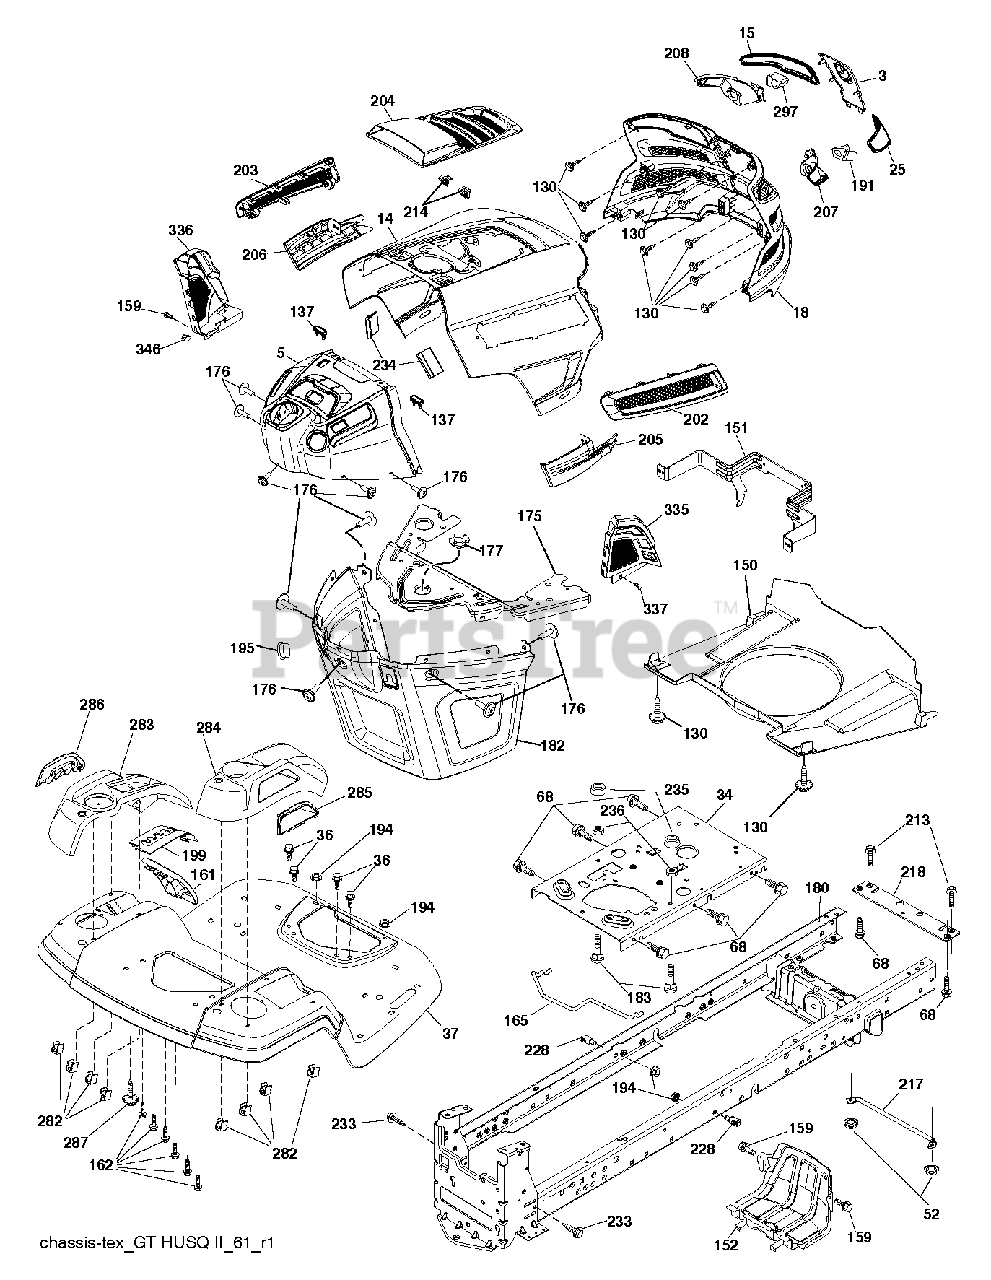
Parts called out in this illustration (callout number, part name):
3	APPLIQUE.SUBASM.GT.HUSQ.II
5	DASH.UPP.GT2.SM.PTO.MCHOKE
14	HOOD.ASM.HUSQVARNA.GT.TEX.ORAN
15	LENS.HEADLIGHT.LH.GTII.2011
18	GRILLE.SUBASM.GT.HUSQ.II
25	LENS.HEADLIGHT.RH.GTII.2011
34	PLATE.ENGINE.WELDED.CHASSIS
36	SCREW 5/16"
37	FENDER.TLT.FS.W/CPH/FW/RSF.668
52	LOCKNUT
68	SCREW LT
130	SCREW.#10 X 0.750.BOS
137	BUMPER DASH
150	AIR.DUCT.GTV.BLACK
151	BRACKET.PIVOT.HOOD.GT.HUSQ.II
152	SHIELD.BROWNING.PNT.GT.V2
159	SCREW, 3/8-16X3/4
161	WINDOW.FUEL.LT.HUSQ.TEX.498
162	SCREW.HI-LO.CONSOLE
165	SUPPORT.TANK.REAR.W/TEX
175	PLATE.CROSSMEMBER.HUSQ
176	SCREW.#10-24X5/8.RN.QU
177	BUSHING, STEERING
180	CHASSIS
182	DASH.LOWER.COMMON.12V.ADAPTOR
183	BOLT.5/16-18X1-1/4 FULL THD
191	INSERT.REFLECTIVE.RH.HUSQ.GTII
194	NUT LOCK HEX FLANGE 5/16-18
195	PLUG.HOLE.DASH.LOWER.12V.BLK
199	PLATE.DECK.LIFT.HUSQ.LT
202	VENT.SIDE.RH.GT.HUSQ.II.
203	VENT.SIDE.LH.GT.HUSQ.II.498
204	VENT.TOP.HUSQ.GT2
205	SIDE.TRIM.RH.GT.HUSQ.II
206	SIDE.TRIM.LH.GT.HUSQ.II.GRAY
207	BEZEL LIGHT.RH.GT.II.MYLAR
208	BEZEL LIGHT.LH.GT.II.MYLAR
213	BOLT
214	CLIP.RETAINER.TINNER.
217	ROD.PIVOT.HOOD
218	X-PIECE.HOOD.STOP.NON/
228	STUD.FASTNER.W/ANTI-ROTATE
233	BOLT.SHOULDER
234	BUMPER.HOOD.TEX.HUSQVARNA
235	SPACER FENDER
236	NUT.CENTERLOCK.5/16-
282	CLIP.RETAINER.CONSOLE.LT.HUSQ
283	CONSOLE.DECK.LIFT.R.SDFL.HUSQ
284	CONCOLE.CNTRL.PDL.HUSQ.LT.498
285	CONSOLE INSERT RH
286	CONSOLE.INSRT.LH.HUSQ.LT.BLACK
287	SCREW 1/4X20
297	INSERT.REFLECTIVE.LH.HUSQ.GTII
335	COVER.RH.CLOSE.OUT.BLACK
336	COVER-LH.LOWER.DASH.GT2.BLACK
337	CLIP.XMAS.TREE.ITW.2622-00
346	CLIP,INSULATOR
